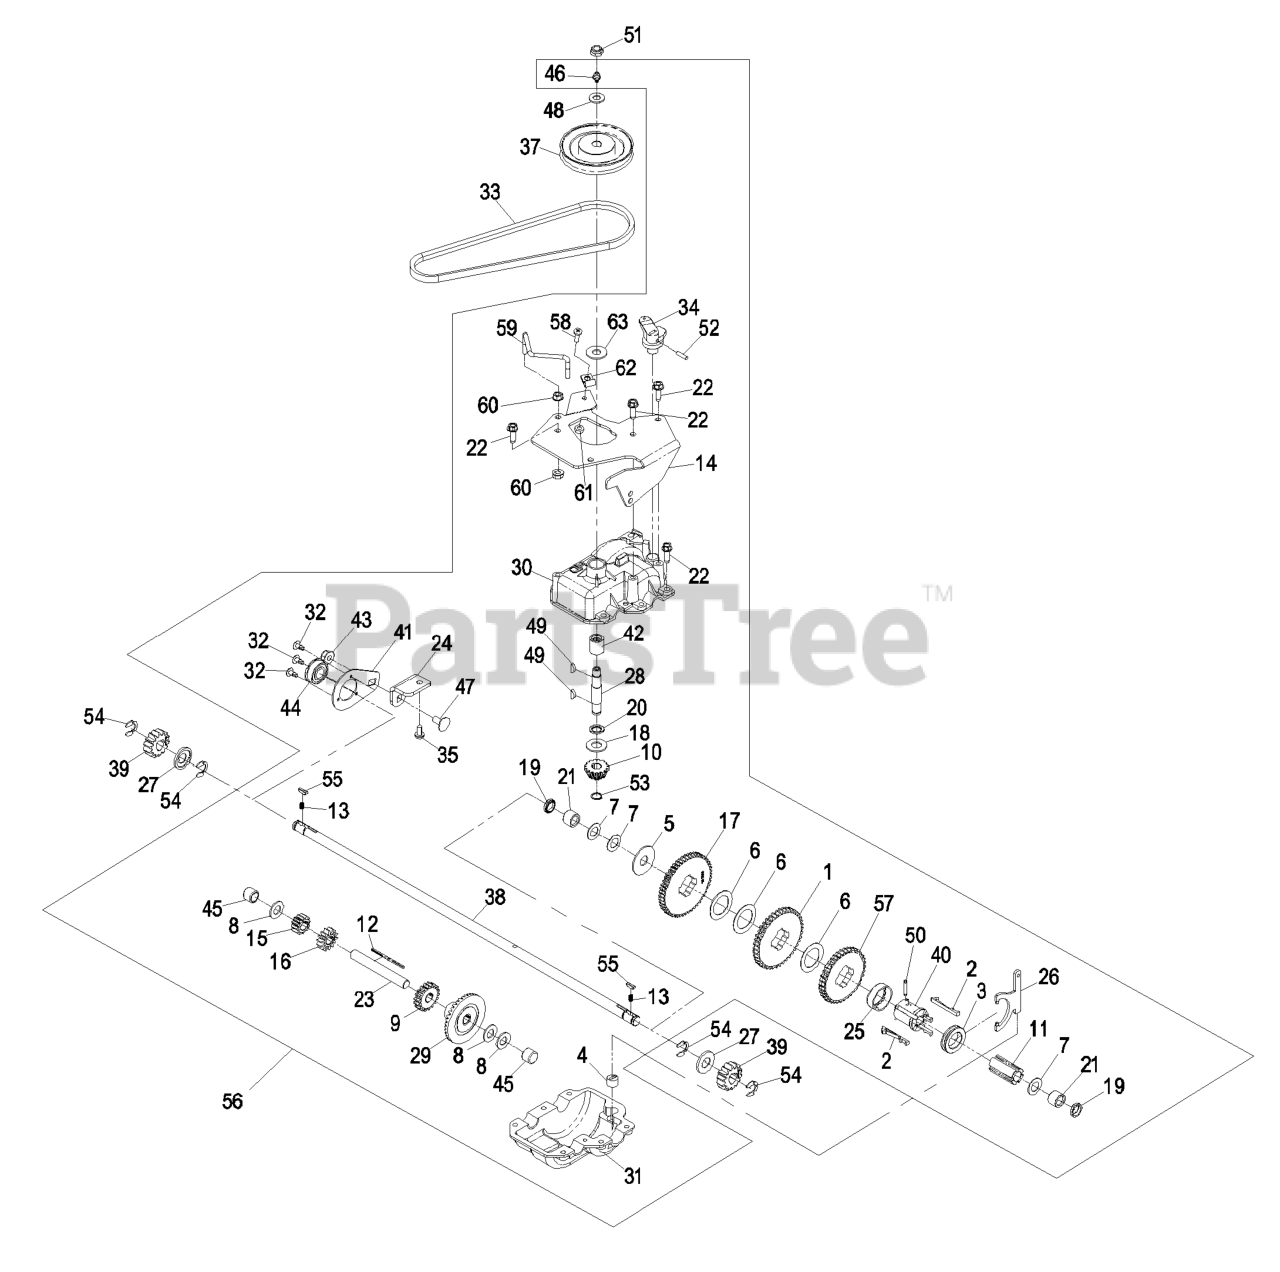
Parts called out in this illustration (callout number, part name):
1	GEAR-42T
2	KEY-SHIFT
3	COLLAR-SHIFT
4	BUSHING-YOKE
7	WASHER-PLAIN
8	WASHER-THRUST
9	GEAR-18T
10	PINION-BEVEL
13	SPRING-COMPRESSION
15	GEAR-12T
16	GEAR-14T
18	WASHER-THRUST
19	SEAL-OIL
22	SCREW-HWHTF
23	SHAFT-INTERMEDIATE
24	BRACKET-BEARING
25	RETAINER-KEY
26	YOKE-SHIFT
27	WASHER-THRUST, OUTER
28	INPUT SHAFT ASM
29	GEAR-BEVEL
30	ASM,GEAR CASE W/BRG
32	SCREW-TAP
33	BELT-V, TRACTION
34	LEVER-SHIFT
35	SCREW-TP
38	SHAFT-AXLE
39	GEAR-PINION
40	SLEEVE-4 DOG
41	PLATE-BEARING
42	BEARING-ROLLER, CAGED
43	NUT-HF, NI
45	BEARING-NEEDLE, CLOSED
46	FITTING-GREASE, ZERK
47	SCREW-CARR
48	WASHER-FLAT
49	KEY-WOODRUFF
50	PIN-GROOVE
51	NUT-HEX
52	PIN-SPRING
53	RING-RETAINING
54	RING-RETAINING
57	GEAR-38T
58	SCREW-HSBH
59	GUIDE-BELT
60	Nut, Whizlock 1/4-20
61	NUT-LOCK, NI
62	R-CLAMP
